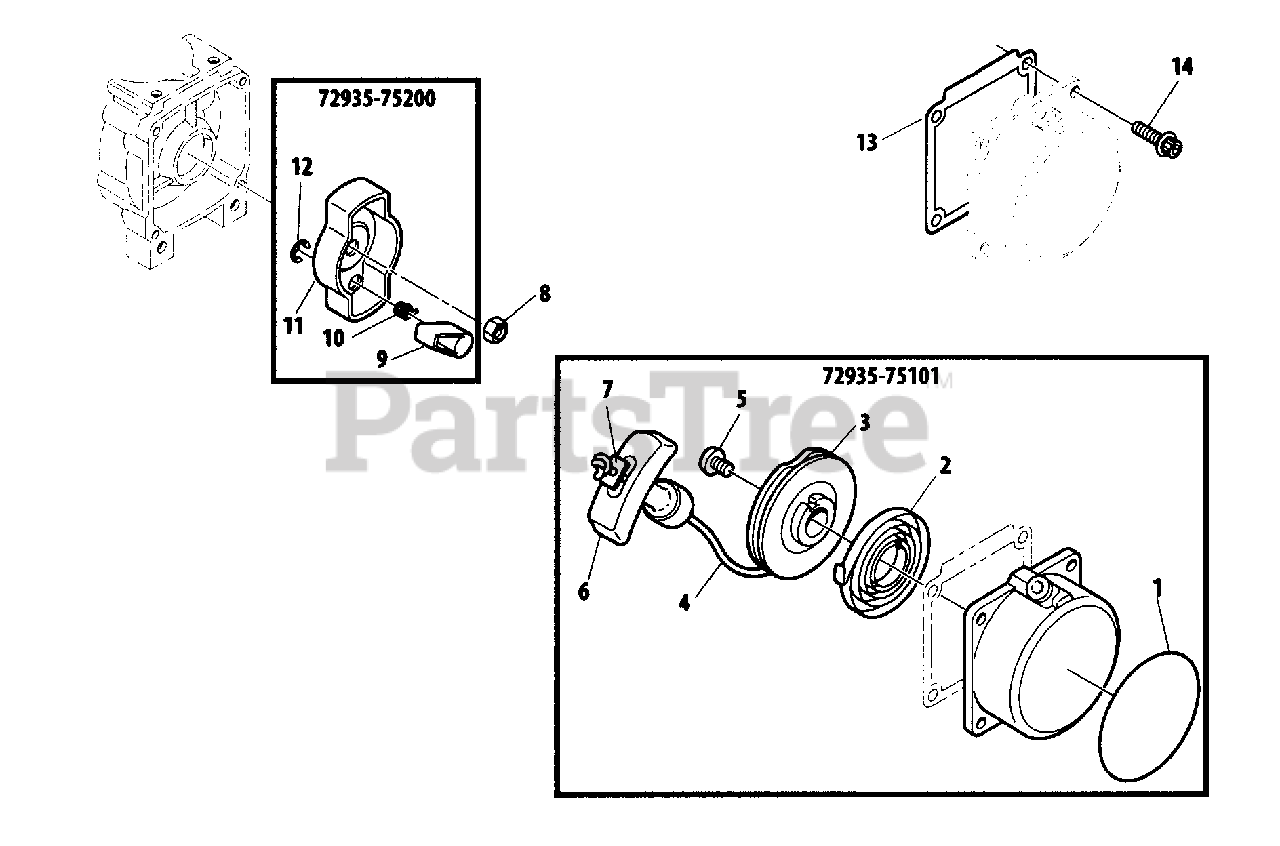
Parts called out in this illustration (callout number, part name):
1	LABEL - MODEL
2	SPRING
3	REEL, ROPE
4	ROPE
5	SCREW -- TAPPING
6	GRIP, STARTER
7	RETAINER, ROPE
8	NUT
9	PAWL, STARTER
10	SPRING, RETURN
11	STARTER PAWL ASSY
12	RING, RETAINING
13	GASKET
14	SCREW - 4X16
72935-75101	STARTER ASSY
72935-75200	STARTER PAWL ASSY
